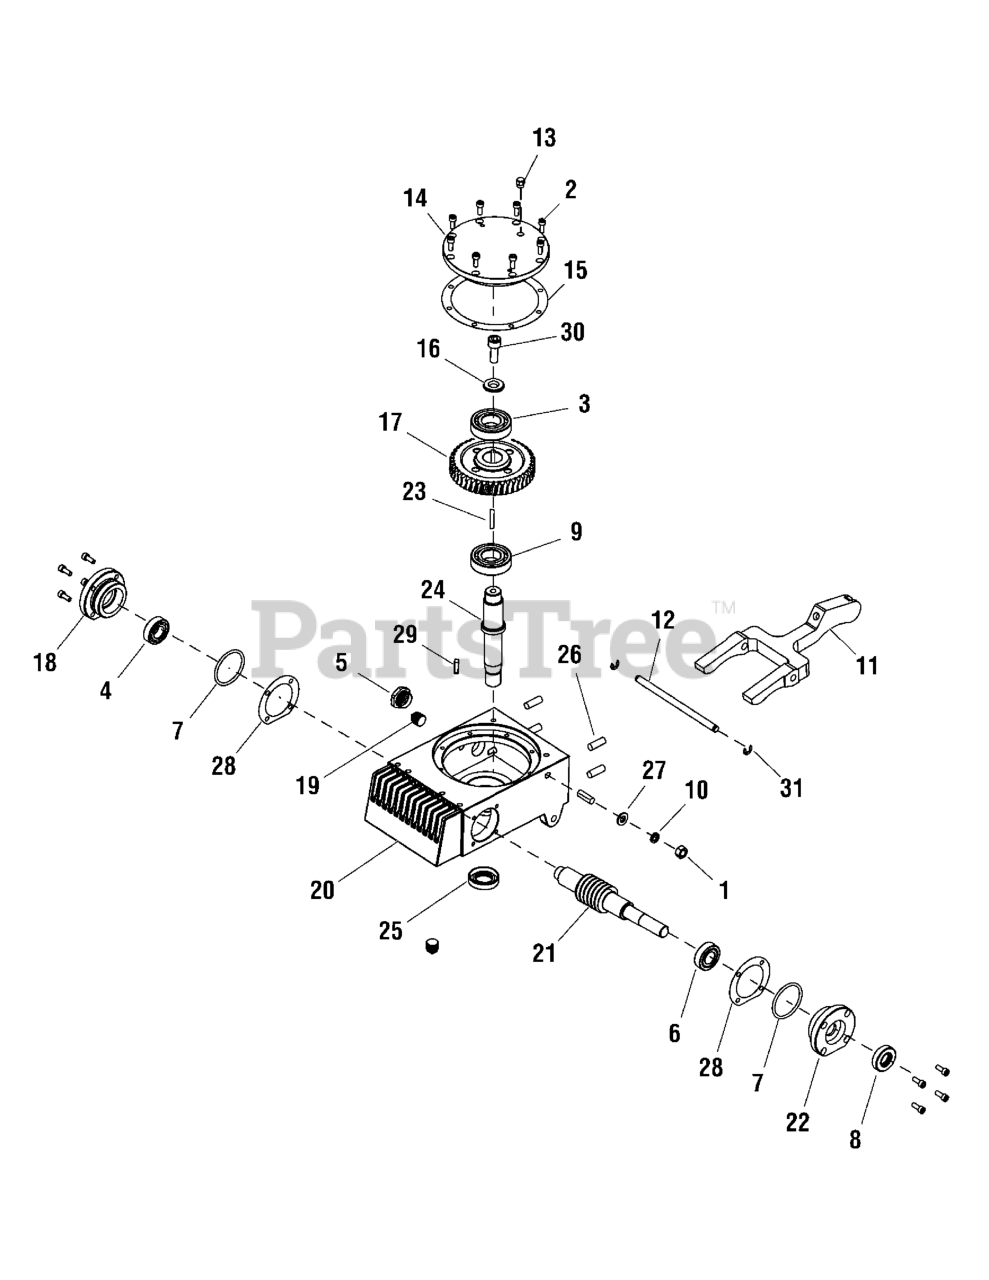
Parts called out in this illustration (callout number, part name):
1	NUT, Hex, M10
2	SCREW, Hex Socket Head, M6 x 16
3	TAPERED ROLLER BEARING
4	BALL BEARING, Deep Groove
5	OIL PLUG
6	TAPERED ROLLER BEARING
7	O-RING
8	OIL SEAL
9	BALL BEARING, Deep Groove
10	WASHER, Spring
11	SHIFTING YOKE
12	SHAFT, Shifting Yoke
13	RELIEF VALVE
14	COVER, Gearbox
15	GASKET, Plastic
16	CLAMPING RING
17	WORM WHEEL
18	BEARING BLOCK, Right
19	SOCKET Hexagonal
20	GEAR BOX
22	BEARING BLOCK, Left
23	KEY, Woodruff, 6 x 10 x 25
24	SHAFT, Worm Wheel
25	OIL SEAL
26	STUD, Double End, M10 x 28-40
27	WASHER, Plain
28	GASKET, Plastic
29	KEY B6 x 25
30	SCREW, Socket Head, M10 x 25
31	CIRCLIP
